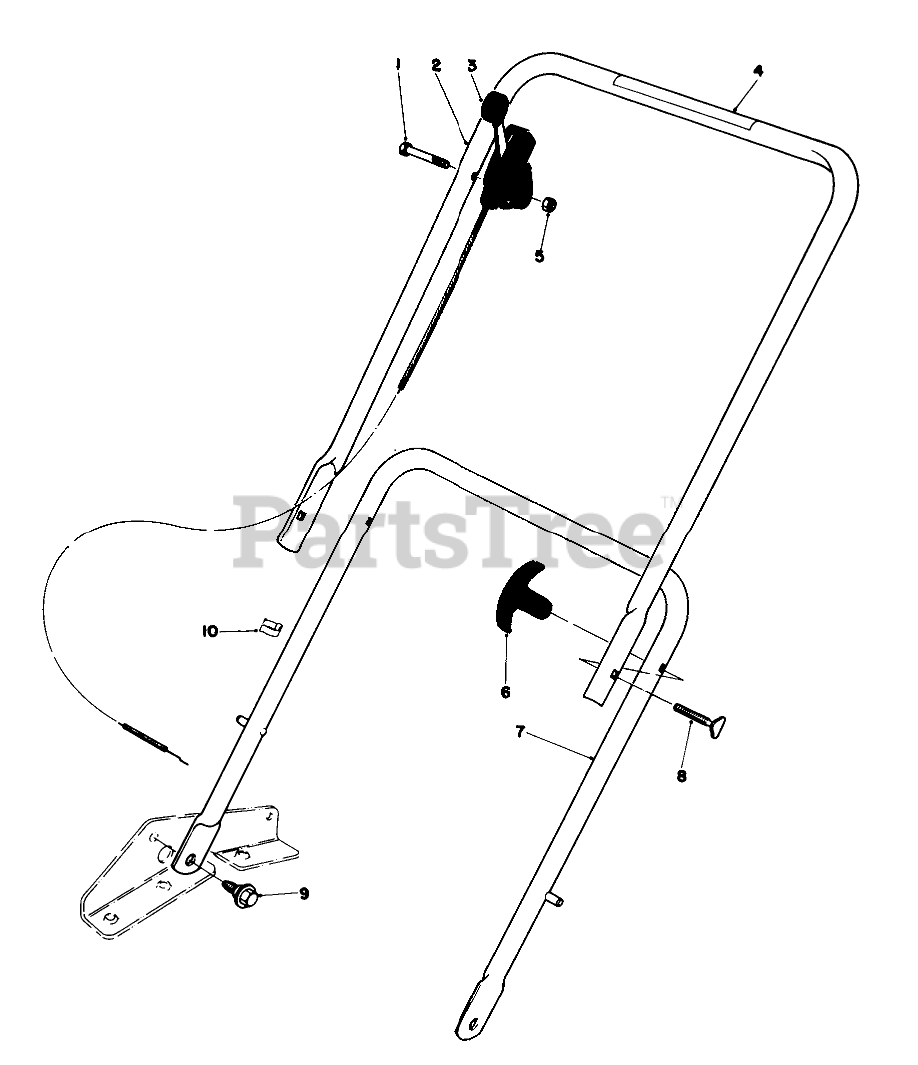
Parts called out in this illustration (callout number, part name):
1	SCREW-HH
2	Upper Handle
3	Throttle Control
4	Decal
5	NUT-LOCK
7	Lower Handle
8	HANDLE SCREW
9	SCREW-SHOULDER
